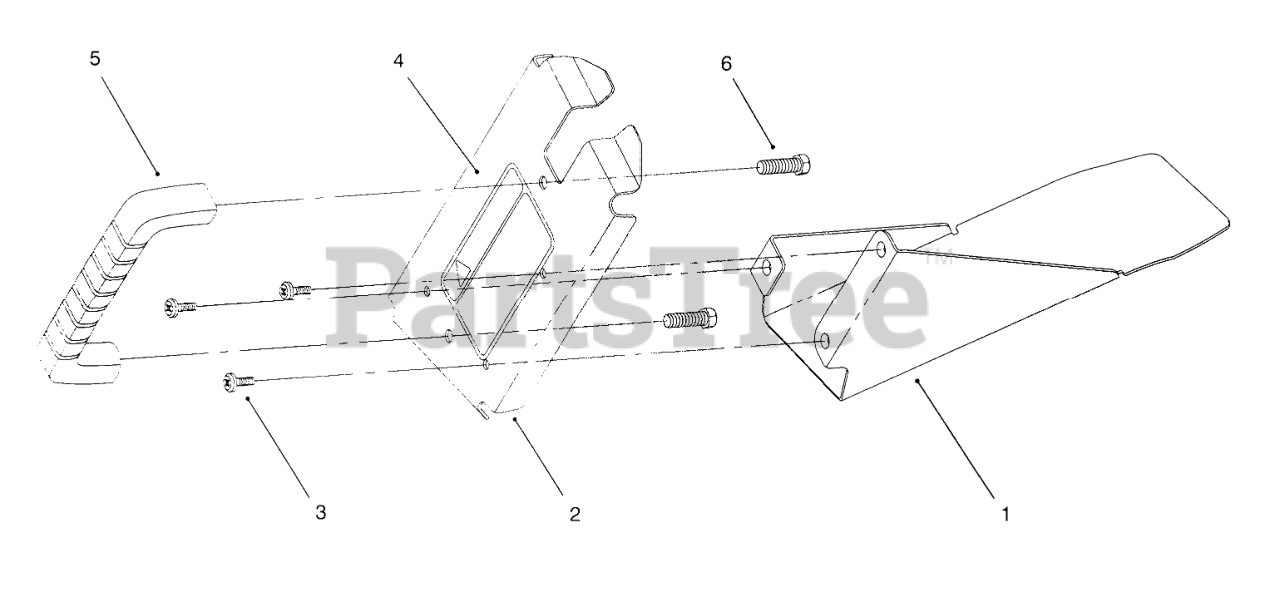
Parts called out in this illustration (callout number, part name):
1	Shield-Discharge Plug
2	Cover-Discharge Plug
4	DECAL - WARNING
5	HANDLE-DOOR
6	SCREW-HWH
